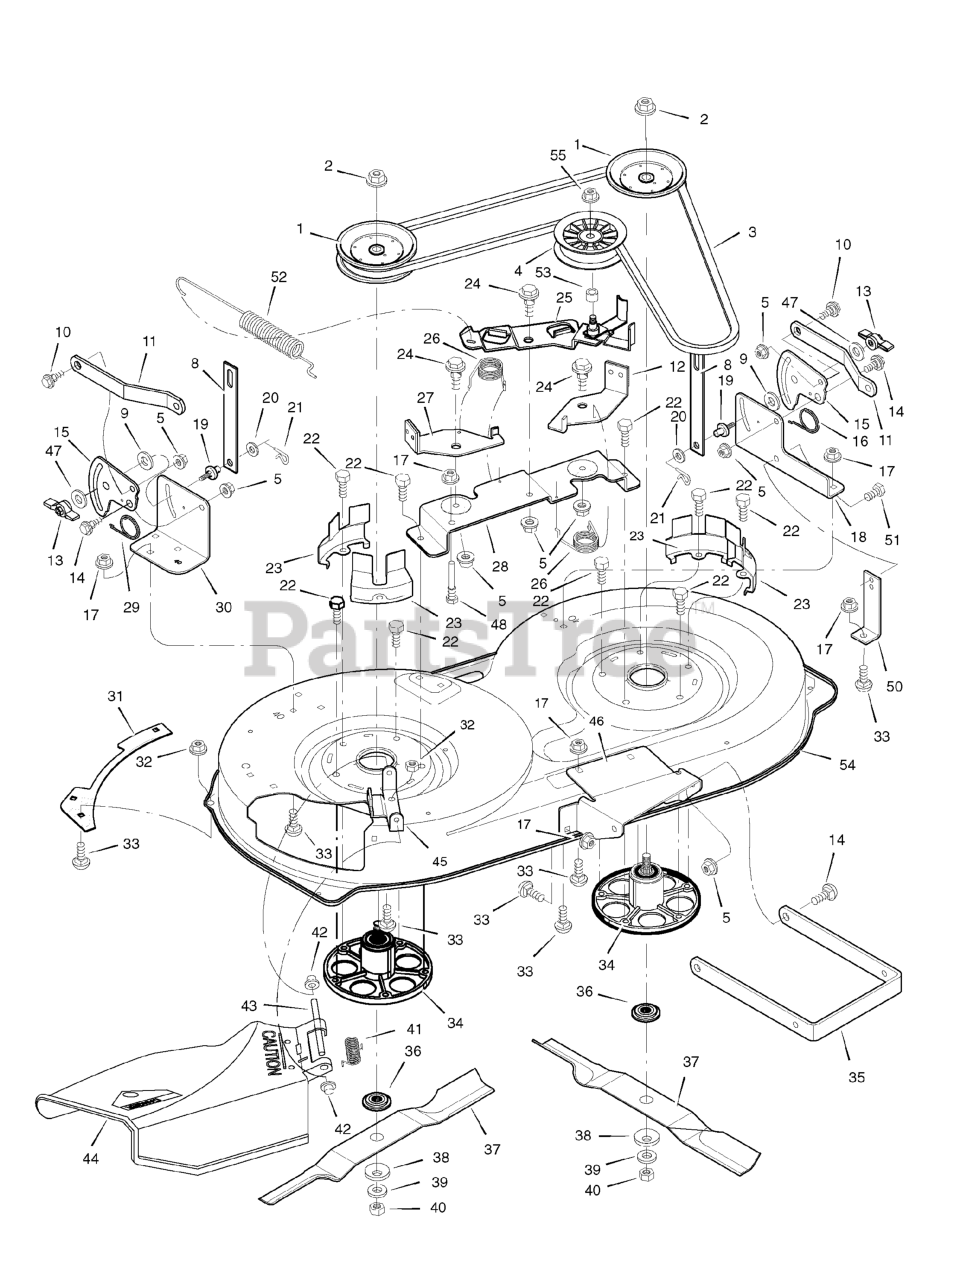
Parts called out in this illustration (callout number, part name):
1	Pulley, Jackshaft
2	Nut, Hex
3	Belt, Mower Drive
4	Pulley, Idler
5	Nut, Flange
8	Link, Lift
9	Pad, Friction
10	Bolt, Shoulder
11	Bracket, Suspension
12	Pad Assembly, Left Brake
13	Knob
14	Bolt, Shoulder
15	Plate, Suspension
17	Nut, Flange
18	Bracket, Suspension
19	Pin, Hanger
21	Pin, Cotter
22	Bolt
23	Cover, Pulley
24	Bolt, Shoulder
25	Arm, Idler
27	Pad Assembly, Right Brake
28	Bracket Assembly, Brake
30	Bracket, Suspension
32	Nut, Flange
33	Bolt, Carriage
34	Mandrell
35	Bracket, Suspension
36	Adapter, Blade
42	Cap, Push On
43	ROD, Deflector
44	Deflector Assembly
45	Bracket, Deflector
46	Bracket, Front Hanger
48	Guide, Belt
50	Bracket, Support
52	Spring, Extension
54	Housing, Blade
55	Nut, Flange
